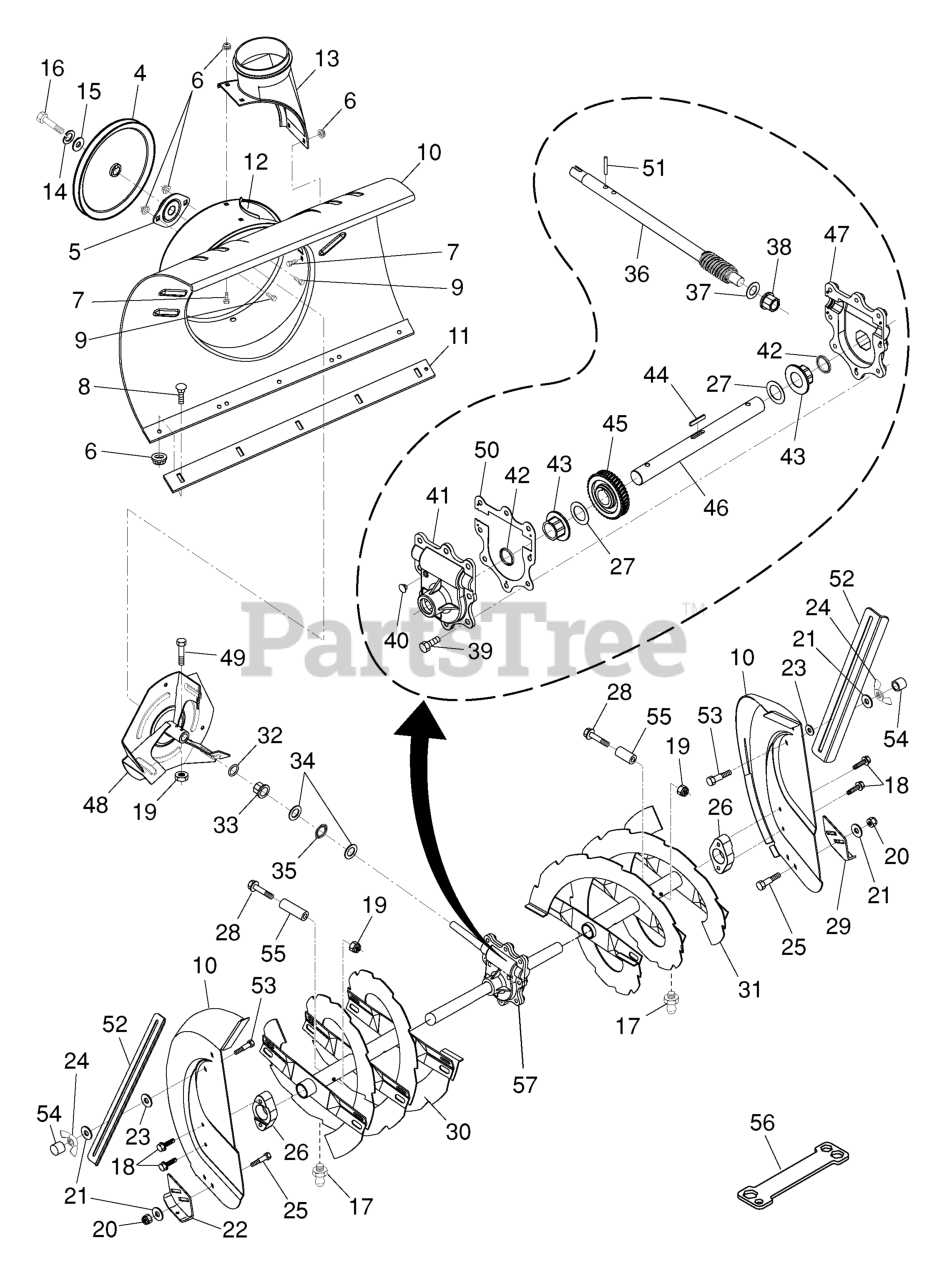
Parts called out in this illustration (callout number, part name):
4	PULLEY, IMPELLER
5	BEARING FLANGE
6	NUT, HEX FLANGE 5/16-18
7	BOLT.CARRIAGE.5/16-18X
8	BOLT
10	HOUSING, AUGER
11	BAR, SCRAPER
12	BRACKET, CORNER DISCHARGE
13	BASE DISCHARGE CHUTE
14	WASHER, LOCK 5/16
15	WASHER, FLAT
16	Screw, Hex Head 5/16-18 x 3/4
17	GREASE FITTING
18	SCREW, HEX HD 5/16X1
19	LOCKNUT.NYLOC.1/4-20
20	NUT, HEX FLANGE 5/16-18
21	WASHER.12021.438X.75X.06.PLS
22	SKID PLATE
24	NUT WING PM
25	BOLT
26	BEARING.BALL.AUGER.SHAFT
27	WASHER TRUST 1"
28	BOLT, SHEAR
30	AUGER ASSY-RH
31	AUGER ASSY-LH
33	BUSHING, FLANGE 3/4
34	WASHER, THRUST 3/4
35	BEARING TRUST 3/4 NTA-1220
36	SHAFT, IMPELLER
37	WASHER, THRUST 5/8
38	BUSHING.FLANGE.(.625X.75)
39	SELF-TAPPING SCREW 5/16-18X3/4
40	PLUG.AUGER.GEAR.BOX.SNOW
41	HOUSING.GEARBOX.RH.SNOW
43	BUSHING FLANGE 1"
44	KEY, SQUARE 1/4 X .875
45	WORM GEAR
46	SHAFT, AUGER
47	LH GEARBOX HOUSING
48	IMPELLER ASSY
49	SCREW.HEX.HD1/4-20X
50	GASKET.AUGER.GEARBOX
51	PIN, ROLL 3/16 X 1-1/8
52	BAR, DRIFT
53	BOLT, HEX HEAD
54	STOP.11261.PLASTIC.30X50L.RED
55	SPACER.3943.SLEEVE.250X.47
56	RP WRENCH, SNOWTHROWER
57	AUGER GEARBOX (COMPLETE)
